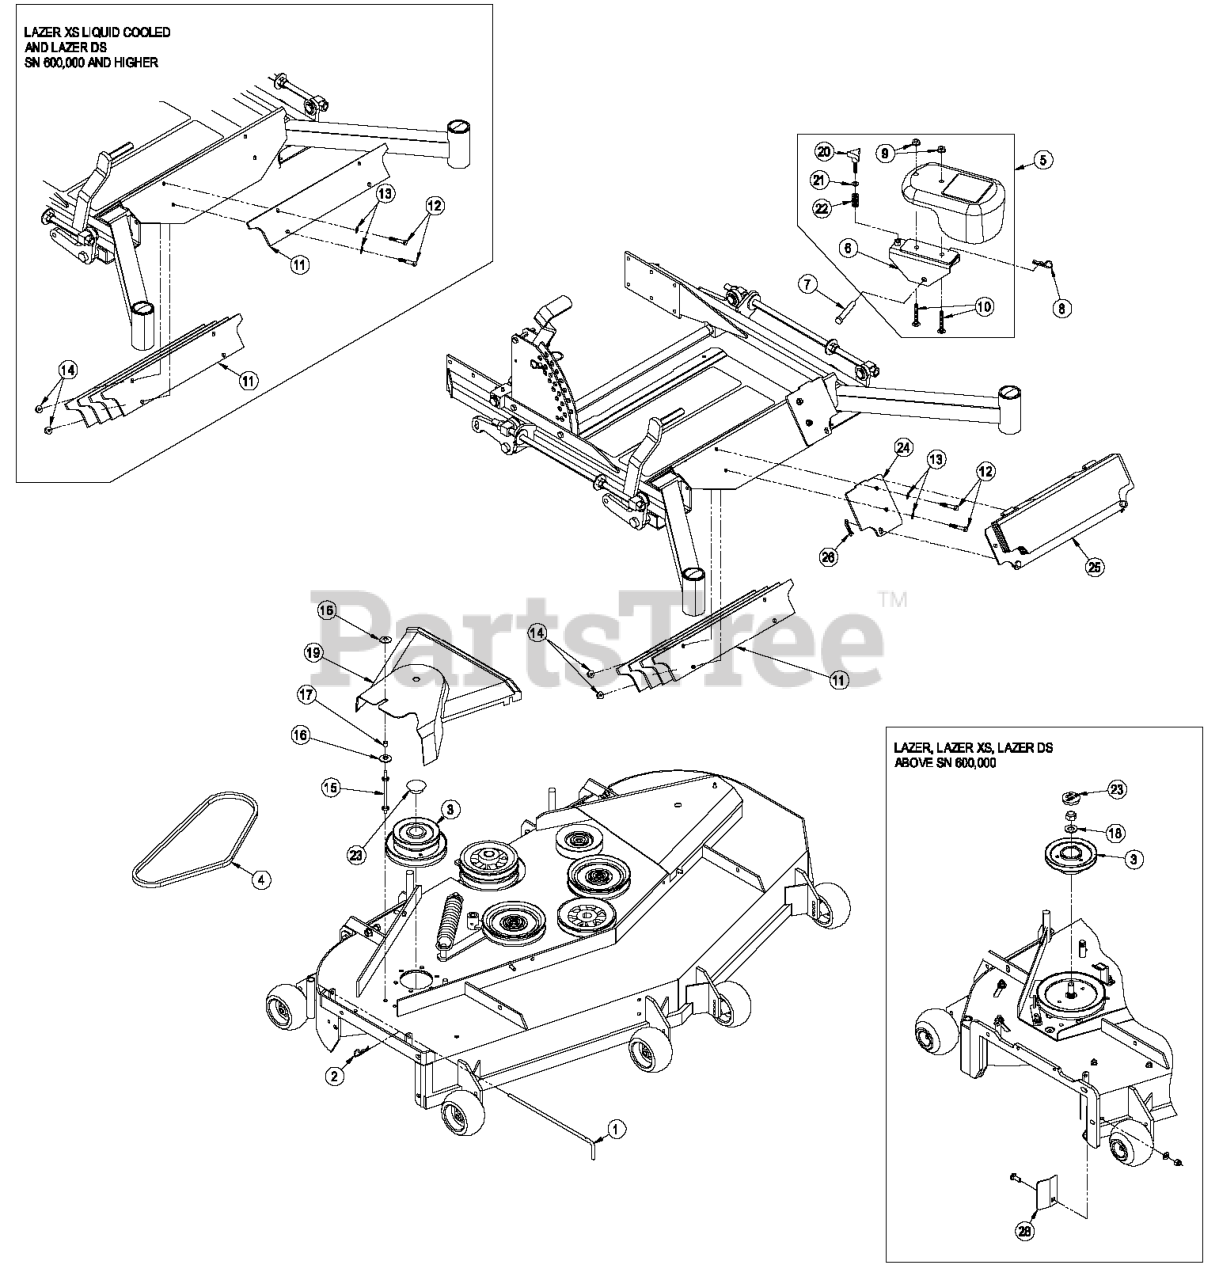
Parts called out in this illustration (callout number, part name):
1	PIN,CHUTE PIVOT
2	PIN-COTTER
3	JACKSHAFT, LZUV72
4	BELT,4L 50.90
5	ASM, WEIGHT 1.5" 70 POUND
6	WLD, BRACKET 2.0 ARM
7	PIN-CLEVIS
8	PIN-COTTER
9	NUT-HHF, WHIZ
10	BOLT-SQH
11	PLATE, WEIGHT
12	SCREW-HH
13	WASHER-PLAIN
14	NUT-HF
15	STUD,BELT SHIELD 4 INCH
16	WASHER-SPRING
18	WASHER-FLAT
19	COVER, BELT 72
21	WASHER-FLAT
23	PLUG, BLACK NYLON 1.75
24	PLATE, WEIGHT MOUNTING
25	ASM, WEIGHT PLATE WITH DE
26	PIN-HAIR
28	DEFLECTOR,LZ UV
